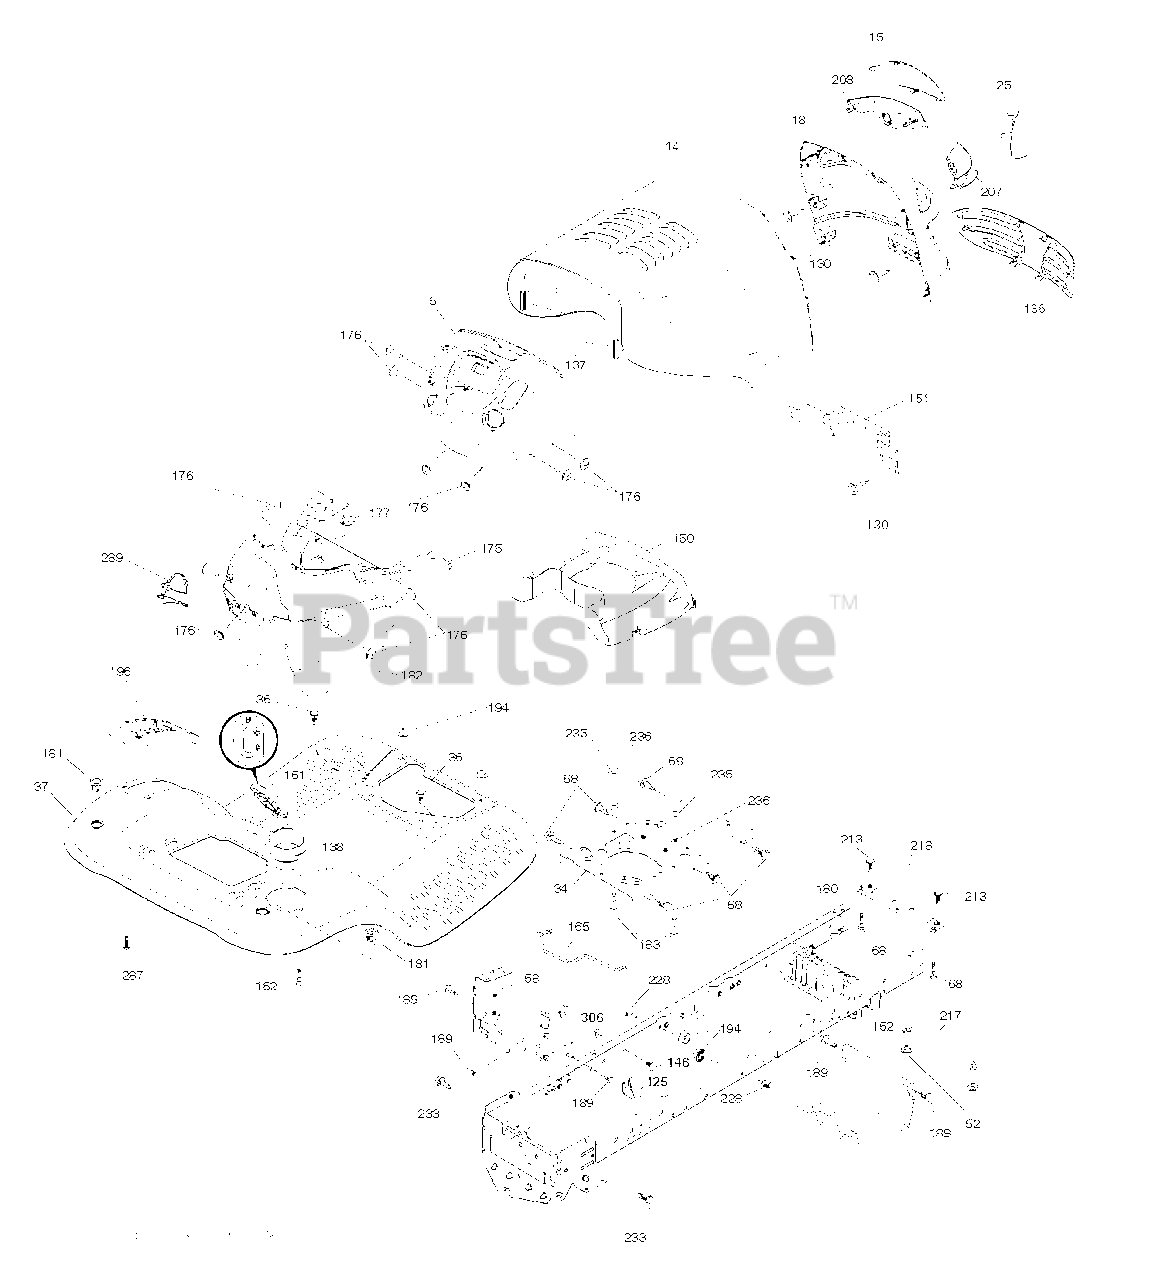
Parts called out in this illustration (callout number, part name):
14	HOOD.STEEL.ELITE.BLACK
25	Grille Lens, Pro RH Clear
34	PLATE.ENGINE.WELDED.CHASSIS
36	SCREW 5/16"
37	FENDER.TLT.FS.W/CPH/FW/RSF.428
52	LOCKNUT
58	DRAWBAR UPPER 2PC SMALL FENDER
68	SCREW LT
125	CLIP.FUEL.LINE
130	SCREW.#10 X 0.750.BOS (2 2)
137	BUMPER.HOOD.LARGE.1.75"
138	CUPHOLDER.TL.TEX.BLACK
146	BOLT.RDHD.SHT.SQNK.3/8-16X5/8
150	AIR DUCT
151	BRACKET PIVOT
152	SHIELD.BROWNING.W/TEX
161	WINDOW.FUEL.LT.TEX.BLACK
162	SCREW.HI-LO.CONSOLE
165	SUPPORT.TANK.REAR.W/TEX
175	CROSSMEMBER.LT
176	SCREW.#10-24X5/8.RN.QU
177	BUSHING STEERING
180	CHASS.WLDMNT.TL.12GA/2P.48/54
181	FEND/FTRST.PCH.CPH.NFW
182	DASH.LOWER.LT.CCS
183	BOLT.5/16-18X1-1/4 FULL THD
189	SCREW
194	NUT LOCK HEX FLANGE 5/16-18
196	CONSOLE.ASM.DECKLFT.BL/RBT.TLT
207	BEZEL.GRILLE.PRO.RH
208	BEZEL.GRILLE.PRO.LH
213	BOLT
217	ROD.PIVOT.HOOD
218	X-PIECE.HOOD.STOP.NON/
228	STUD.FASTNER.W/ANTI-ROTATE
233	BOLT.SHOULDER
235	SPACER FENDER
236	NUT.CENTERLOCK.5/16-
287	SCREW 1/4X20
289	PLUG CRUISE HOOK PHONE
306	NUT LOCK FLG 3/8-16 UNC
